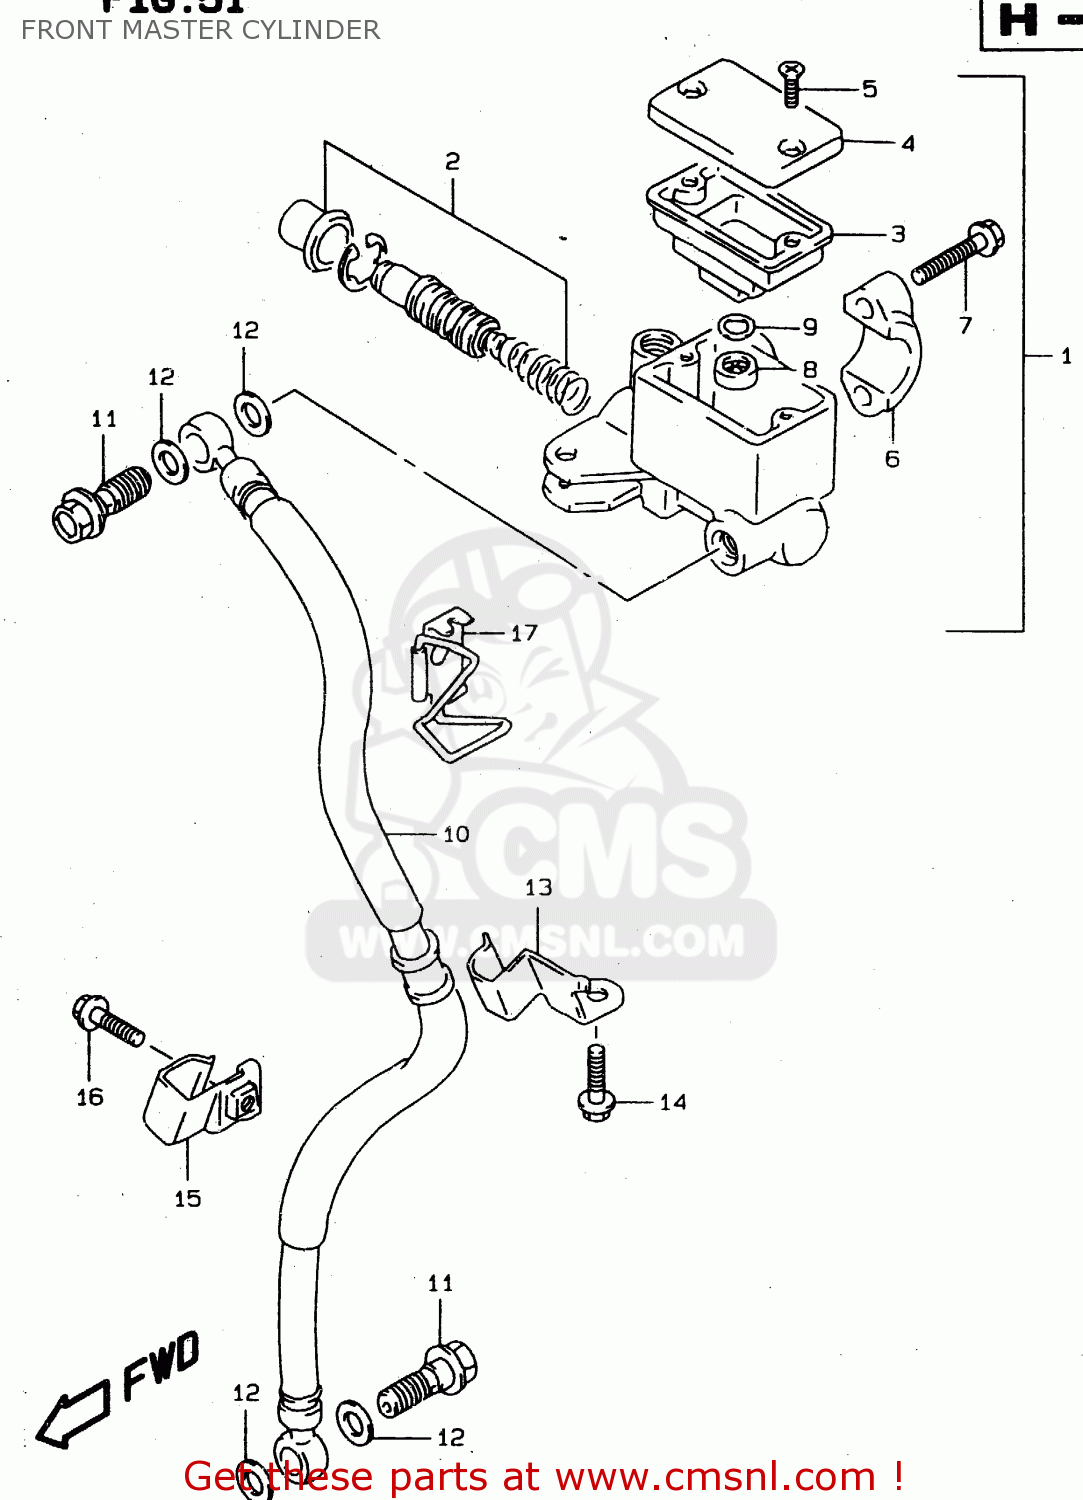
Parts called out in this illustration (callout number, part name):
1	CYLINDER ASSEMBLY,FRONT MASTER
2	PISTON/CUP SET
3	DIAPHRAGM
4	CAP
5	SCREW
6	HOLDER
7	BOLT(6X25)
8	SEPERATOR
9	PLATE
10	HOSE,FR BRAKE
11	BOLT UNION
12	WASHER(10X15X1.5)
13	CLAMP, BRAKE HOSE UPPER
14	BOLT
15	CLAMP,FR BRAKE HOSE LWR
16	BOLT
17	GUIDE,FR BRAKE HOSE
